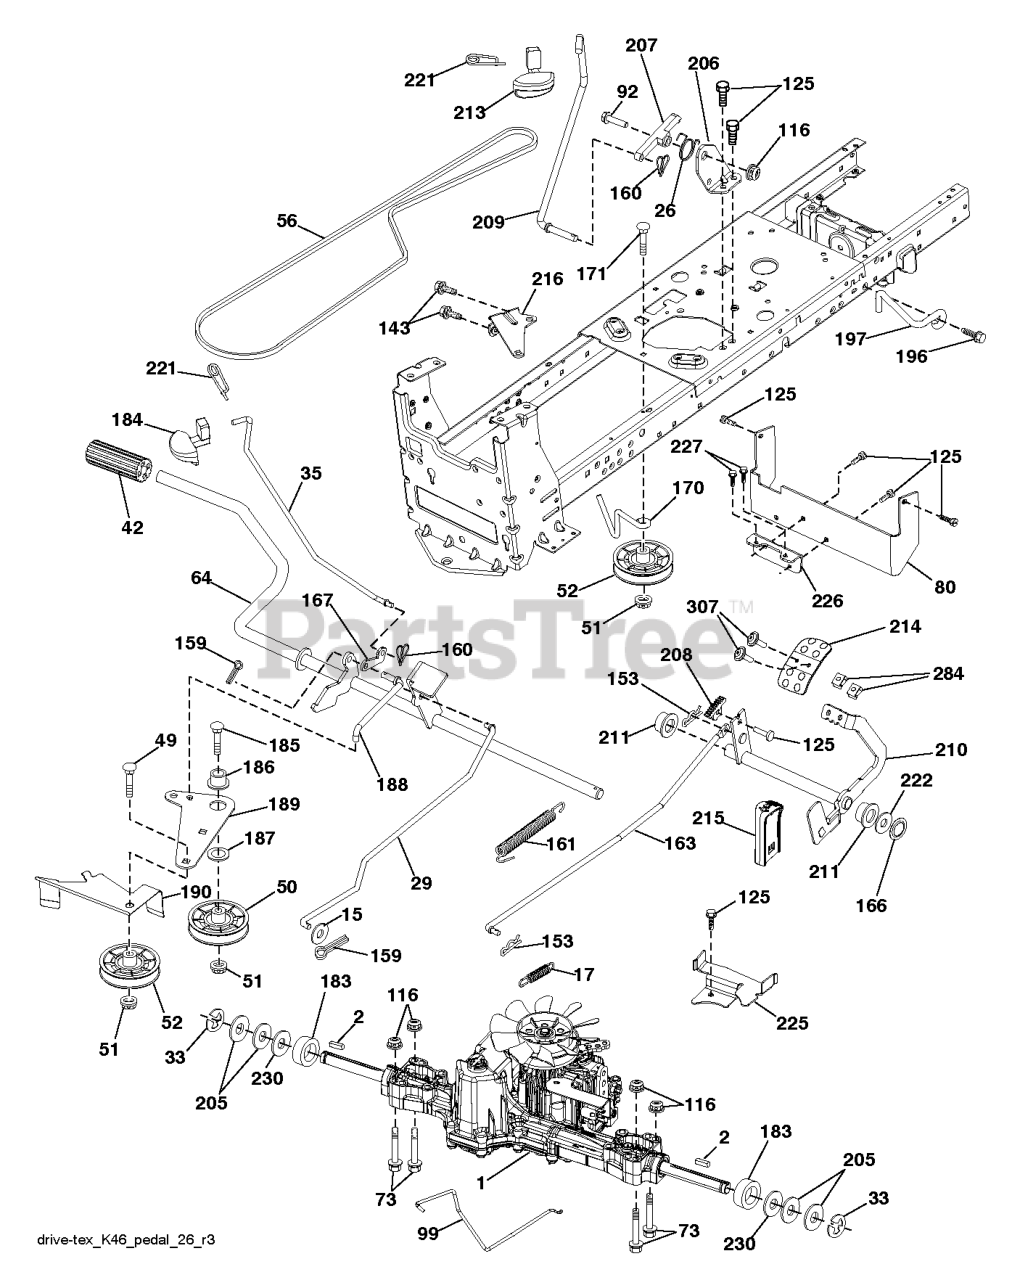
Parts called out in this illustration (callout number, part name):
2	SQUARE KEY
15	WASHER
17	SPRING.BRAKE.K46.GREEN
26	SPRING.RETURN.CRUISE
29	ROD.BRAKE.K46
35	ROD .BRAKE. PARKING. GT. HUSQ.
42	PEDAL COVER T
50	IDLER.FLAT.910.OFFSET
51	NUT LOCK FLG 3/8-16 UNC
52	IDLER.V-GROOVE.910.OFFSET
56	V-BELT.MOWER.92.40.42/K46
64	SHAFT.ASM.PEDAL.BRK.CNTR
73	BOLT
80	STRAP.TORQUE.K46.K57R.TT
92	BOLT
99	ROD.SPRING.BYPASS.K46.LT.Z
116	NUT LOCK HEX FLANGE 5/16-18
125	SCREW
143	SCREW LT
153	RETAINER M
159	COTTER PIN
160	RETAINER CLIP
161	SPRING, RETURN LT
163	ROD.CONTROL.K57R.K46
166	NUT.PUSH.625
167	LATCH.BRAKE.SPRING
170	KEEPER.V-IDLER.CENTER.
171	BOLT
183	SPACER AXLE
184	RB HANDLE.PARKG.BRK.HUS/PRED
186	SPACER.RETAINER
187	WASHER 12/32X2X10GA
188	RP.LINK.CLUTCH.GROUND.DRIVE
189	BELLCRANK.GROUND.DRIVE.TEX.
190	KEEPER.BELLCRANK.DRIVE
196	SCREW 3/8-16X1
197	LINK.CLUTCH.ANIT-ROTAT
206	BRACKET.MOUNT.CRUISE.LATCH
207	LATCH.CONTROL.CRUISE
208	GEAR.SECTOR.CONTROL.CR
209	ROD.CONTROL.CRUISE.GT.
210	ROCKER.ASM.PEDAL.CONTR
211	BEARING.NYLON
213	KNOB.CONTROL.CRUSIE.HU
214	PEDAL.FORWARD.HUSQVARNA.DEALER
215	PEDAL.REVERSE.TEX.GT.4
216	BRACKET.PULLEY.IDLER.W/TEX
221	RETAINER.SPRING.CLIP.H
222	WASHER 21/32 X 1-1/4 X 10 GA.
225	KEEPER.BELT.TRANSAXLE.K46
226	BRACKET.MOUNT.TORQUE.K46.TLT
227	SCREW.THDROL.5/16-18X3/4.TTY
230	WASHER.HARDENED
284	NUT.U-CHNL.1/4-20.550DP.350PNL
307	SCREW.MACHINE.CR.1/4-20
